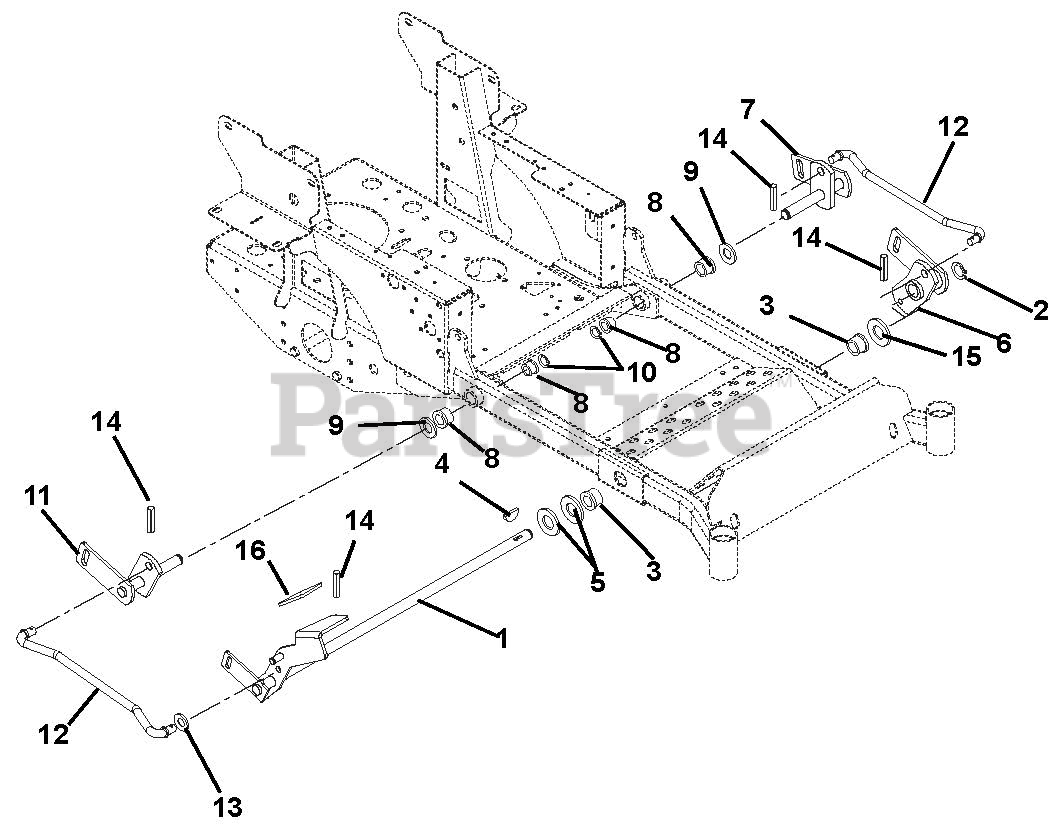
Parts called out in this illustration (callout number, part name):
1	Weldment, Mechanical Deck Lift
2	Ring, Retaining External 1.00 x .078
3	Bushing, Flange Nylon 1.020 x 1.385 x .75 x 1.75
4	Key, Woodruff .25 x 1.00
5	Washer, Flat Steel 1.062 x 2.0 x .134
6	Weldment, Left Hand Mower Lift Arm
7	Weldment, Left Hand Rear Mower Lift Arm
8	Bushing, Flange Nylon .762 x 1.0 x .580 x 1.48
9	Washer, Hardened Steel .758 x 1.23 x .031
10	Ring, Retaining External .689 x .077
11	Weldment, Right Hand Rear Mower Lift Arm
12	Rod, Lift Assist
13	Washer, Flat Steel .630 x 1.25 x .062
14	Pin, Roll .25 x 1.25 Stainless Steel
15	Washer, Hardened Thrust 1.00 x 1.55 x .03
16	Grip, Pedal
